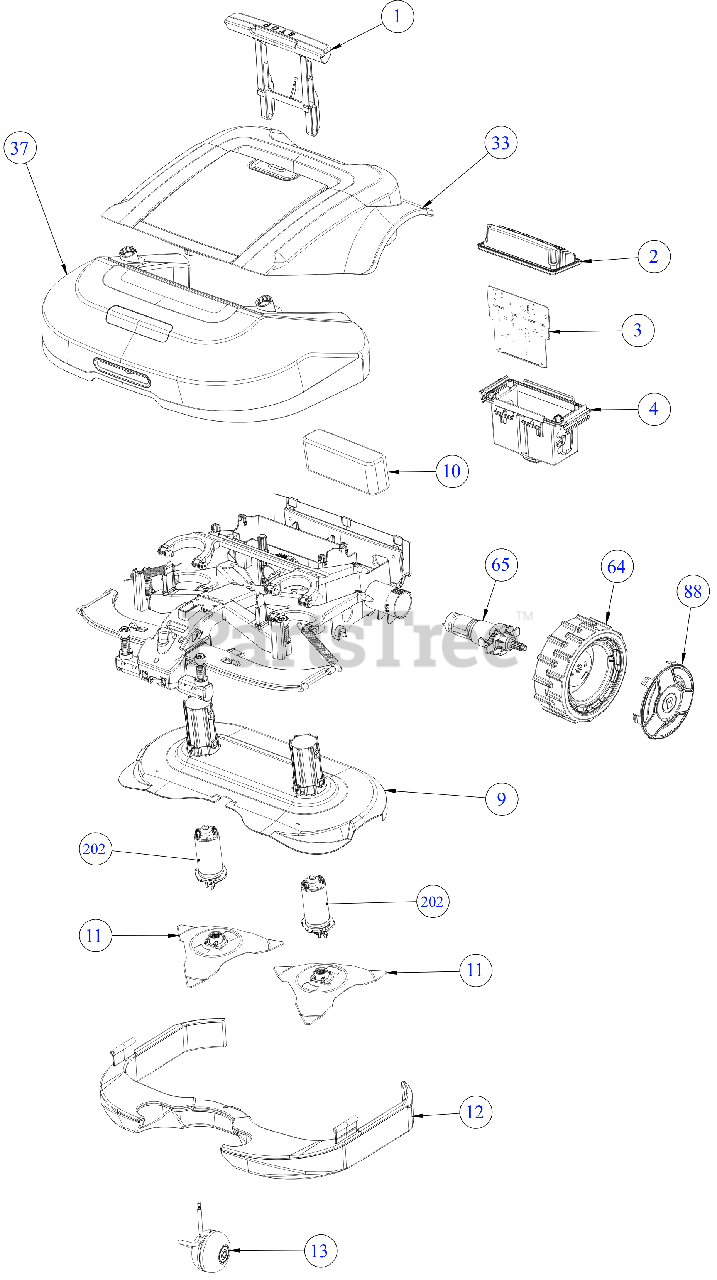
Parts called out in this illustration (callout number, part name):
1	CARRYING AND STOP HANDLE
2	LCD PANEL ASSEMBLY
3	RS MAIN RED (2018)
4	C-BOX ASSEMBLY
5	DRIVE MOTOR ASSEMB
8	WHEEL LOCK
9	MOWING DECK ASSEMB
10	BATTERY-RS630 (6AH
11	2 BLADE KIT-RS MOD
12	FLOATER ASSEMBLY
13	FRONT WHEEL ASSEMBLY (2014)
14	WIRE LOCKER
15	MOWING UPPER ARM
16	MOWING MOTOS LOCKE
17	MOWING LOWER ARM
18	BALL JOINT ASSEMBL
19	SHAFT-PARRAL ASSEM
20	FLOATER SPRING
21	WING LEFT
22	WING TO FLOATER SHAFT
23	WIRE SENSOR CAP
24	Y SHAFT TO WING
25	MOWING DECK SPRING
27	WING RIGHT
29	FRONT WHEEL MAGNET
31	CHASSIS ASS S MODE
32	Y ARM SNAP
33	COVER ASSEMBLY (GREEN)
34	RS DOOR SHUTTER KIT
36	C-BOX RUBBER DOOR
37	BUMPER ASSEMBLY BLACK
38	LIGHT COVER-BUMPER
39	BUMPER HANG CAVITY
40	BUZZER BRACKET
41	PIEZO BUZZER W/CAB
42	BASE STATION W/O H
43	FASTENING STAKES-B
47	20M CABLE-PBOX TO STATION
49	WIRE SENSORS CABLE W/HOLDERS
50	FUSE-BATTERY CABLE
51	MAIN BOARD TO DRIVE MOTOR CABLE
52	MAIN BOARD TO BATTERY CELLS CABLE
55	FUSE THREAD
56	FUSE-32V/20A FAST
57	FRONT WHEEL SLEEVE
64	POWER WHEELS (W/CAP)
65	HD DRIVE MOTOR ASMALUMINUM SPLINE
67	FRONT BOARD S (2018 RED)
69	32 VOLT INDOOR SWITCH 3.5A IP67
70	RS CHARGING ADAPTOR (2018)
71	MAIN BOARD TO FRT WHEEL CABLE (18)
72	RS COMM/GSM SPLIT CABLE PCG6200
73	GSM/RCM (ALL MODELS)
88	RS PREMIUM TAS
202	MOWING MOTOR BRUSH
203	POWER BOX HANGING BRACKET
204	SCREW + "DIBEL" X 2 KIT
207	MINI JUMPER 2.54MM
208	STAKE-PERIMETER SW
210	PERIMETER SWITCH (ESB5009F)
211	BATTERY PACK-PERIM
212	PERIMETER SWITCH B
213	PERIMETER SWITCH STICKER
